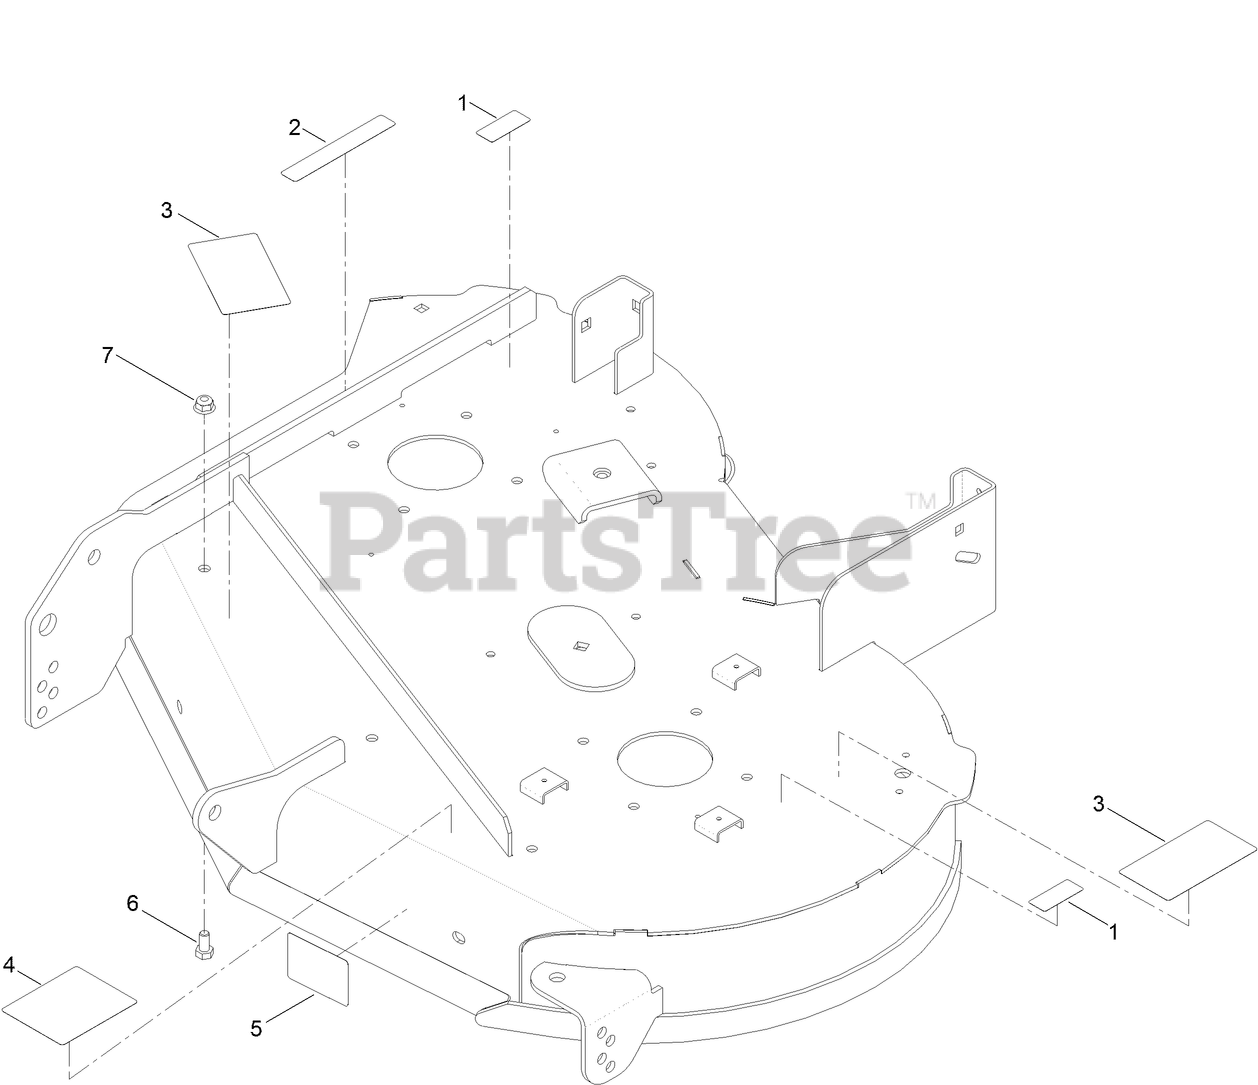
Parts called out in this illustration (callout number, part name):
1	DECAL-DANGER
2	DECAL-DANGER
3	DECAL-DANGER
4	DECAL-ROUTING, BELT
5	DECAL-SCALP, ANTI
6	SCREW-HH
7	NUT-HF, NI
